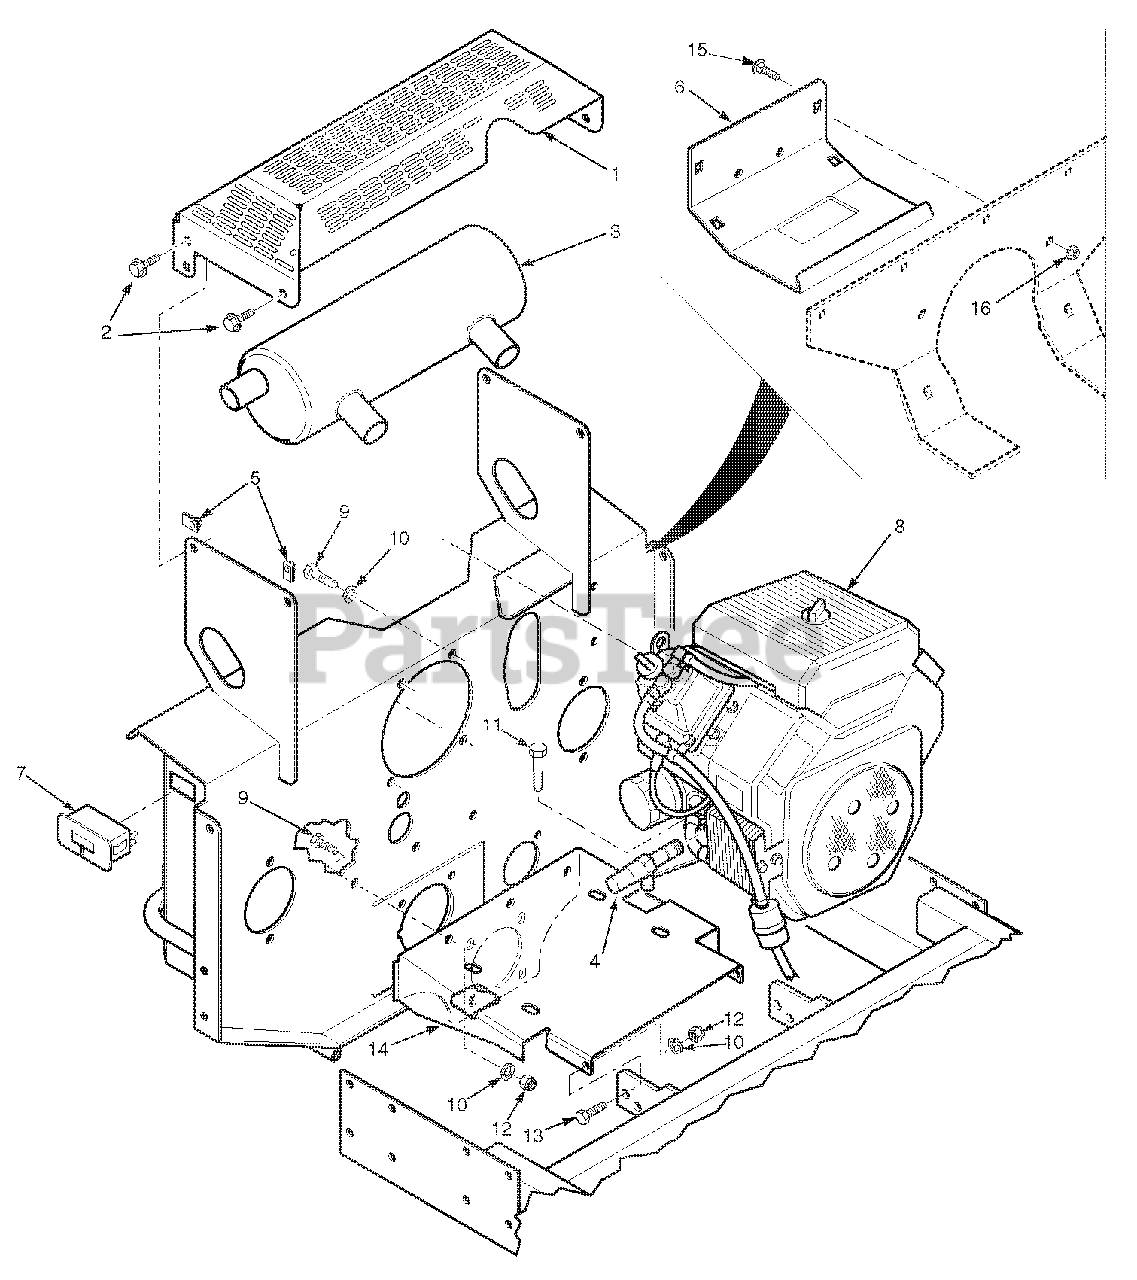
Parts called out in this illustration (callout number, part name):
1	Muffler Guard
2	Screw, Hex Serrated Flange 1/4-20 x 3/4"
3	Muffler, Part Of Engine
4	Oil Drain Extension
5	U-Nut, 1/4-20
6	Rear Cover
7	Hour Meter, Inductive
8	Engine, Kohler 21 CH LP
9	Bolt, Hex Head 3/8-16 x 1"
10	Lockwasher, 3/8" Spring
11	Bolt, Hex Head 3/8-16 x 1-3/4"
12	Nut, Hex Elastic Stop 3/8-16
13	Bolt, Hex Head 3/8-16 x 1-1/4"
14	Plate, Engine Mounting
15	Bolt, Carriage 5/16-18 x 3/4"
16	Nut, Hex Serrated Flange 5/16-18
